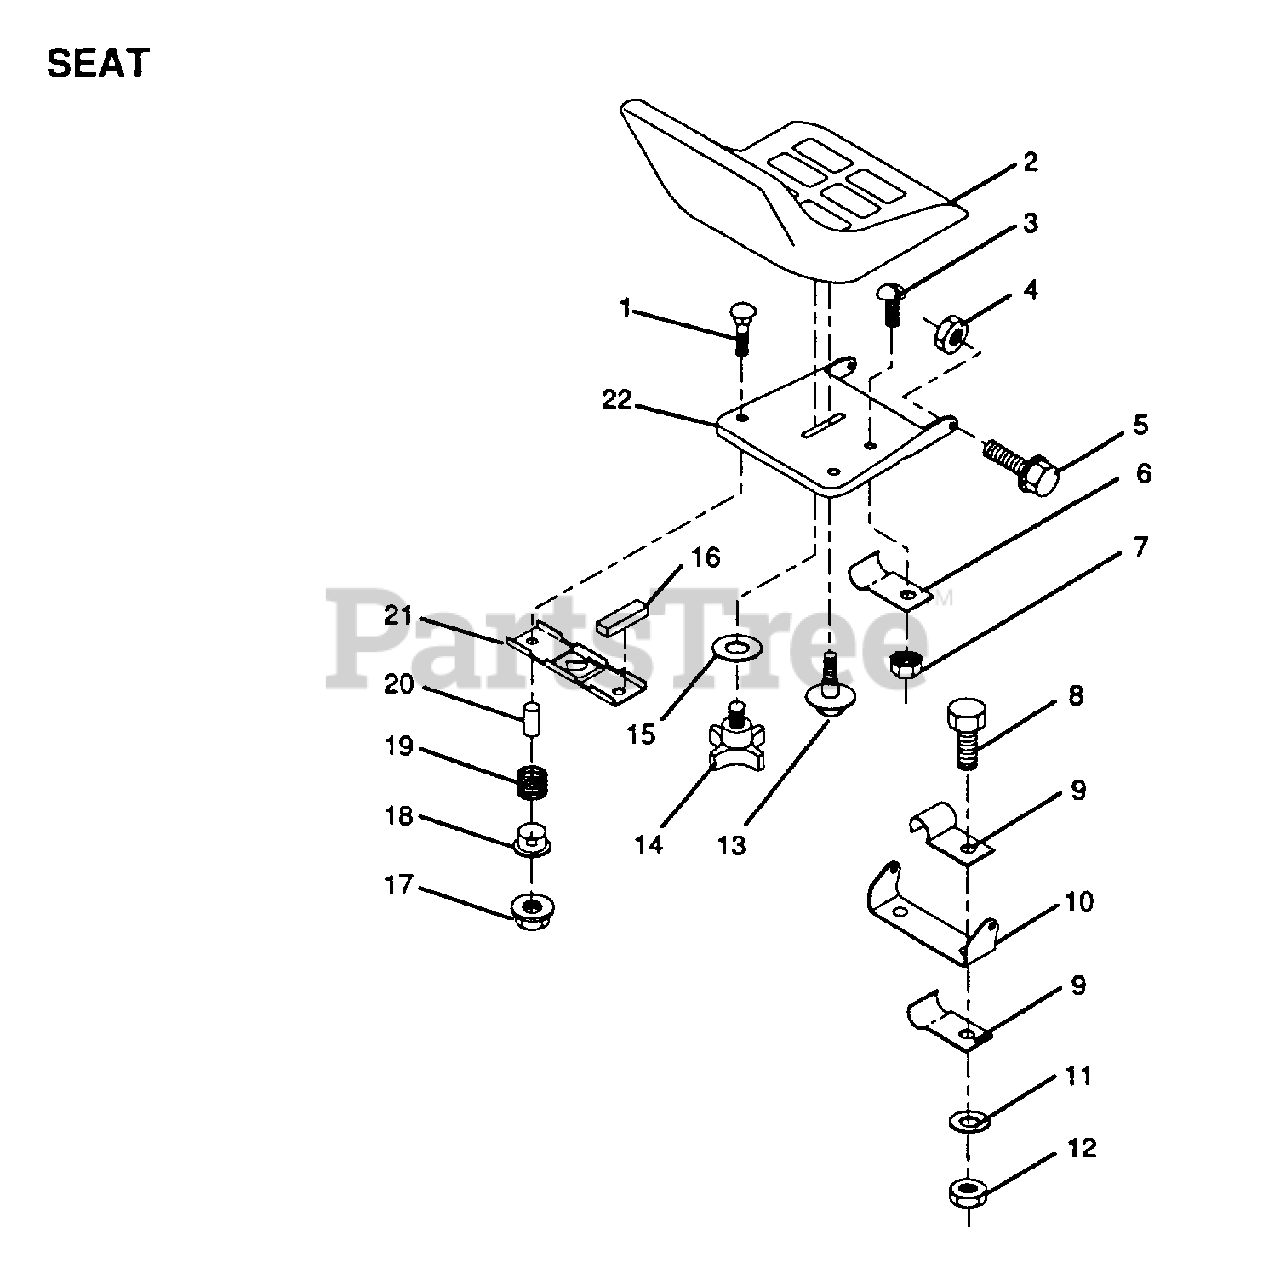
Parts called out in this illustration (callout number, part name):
1	BOLT
7	"NUT,KEPS"
9	CLIP T
11	WASHER
14	"KNOB 1/2"" YT"
15	WASHER
16	STRIP FORM
18	BUSHING
19	SPRING
20	SPACER SPLIT
21	BRKT SWITCH
